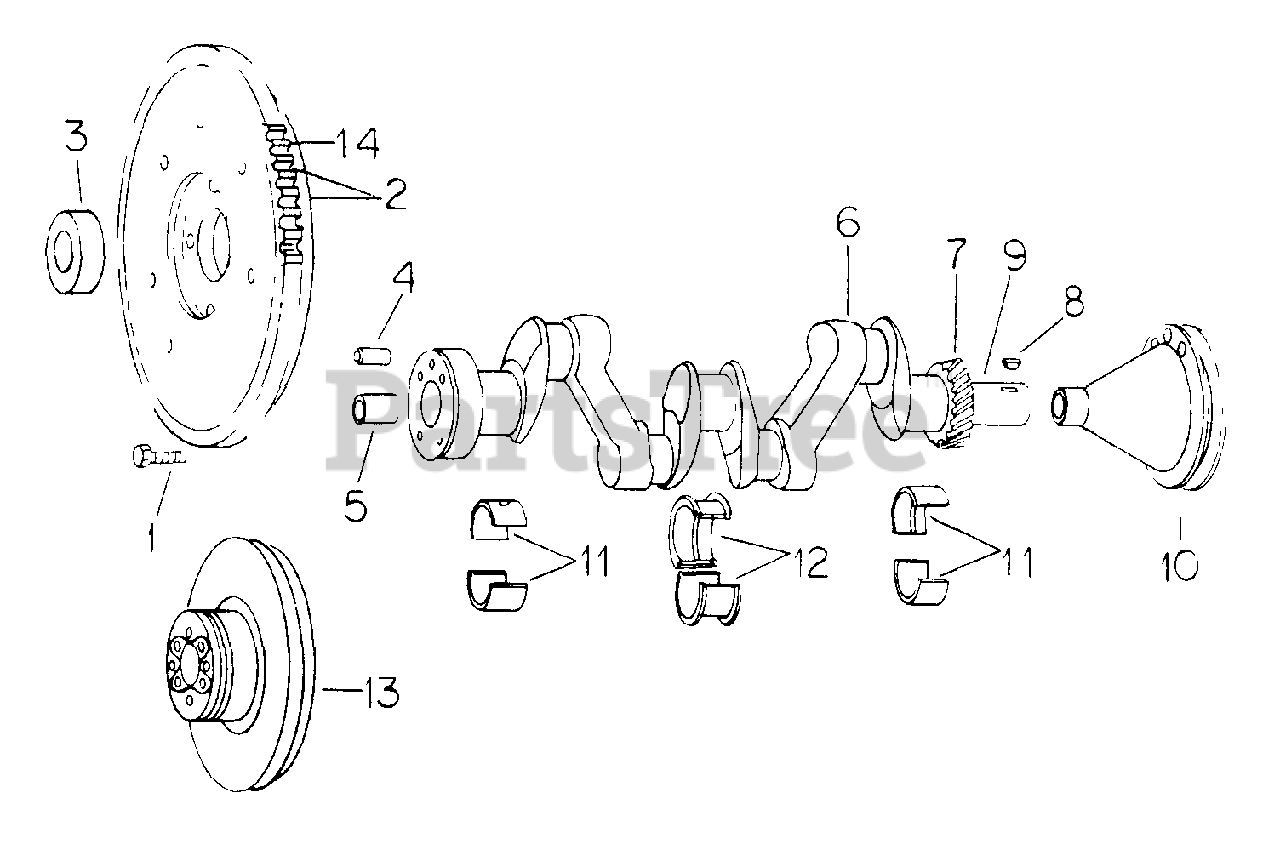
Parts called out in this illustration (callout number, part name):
1	BOLT, 3/8-24 X 1-1/4 TYPE 4 FLYWHEEL USED
2	FLYWHEEL, CLUTCH FORWARD
3	BEARING, CLUTCH PILOT
4	PIN, FLYWHEEL DOWEL
5	BUSHING, CLUTCH PILOT
6	CRANKSHAFT W/BEARINGS - STD
7	PINION, CRANKSHAFT - 18 T
8	KEY, 5/32 X 5/8 WOODRUFF 6 ALY-STL - CRANKSHAFT PINION
9	KEY, 5/32 X 5/8 WOODRUFF 6 ALY-STL - FAN DRIVE PULLEY
10	PULLEY, FAN DRIVE
11	BEARING ASSY, CRANKSHAFT FRONT AND REAR STD
12	BEARING ASSY, CRANKSHAFT CENTER .010 U/S
13	FLYWHEEL
14	GEAR, FLYWHEEL RING - 84 T
